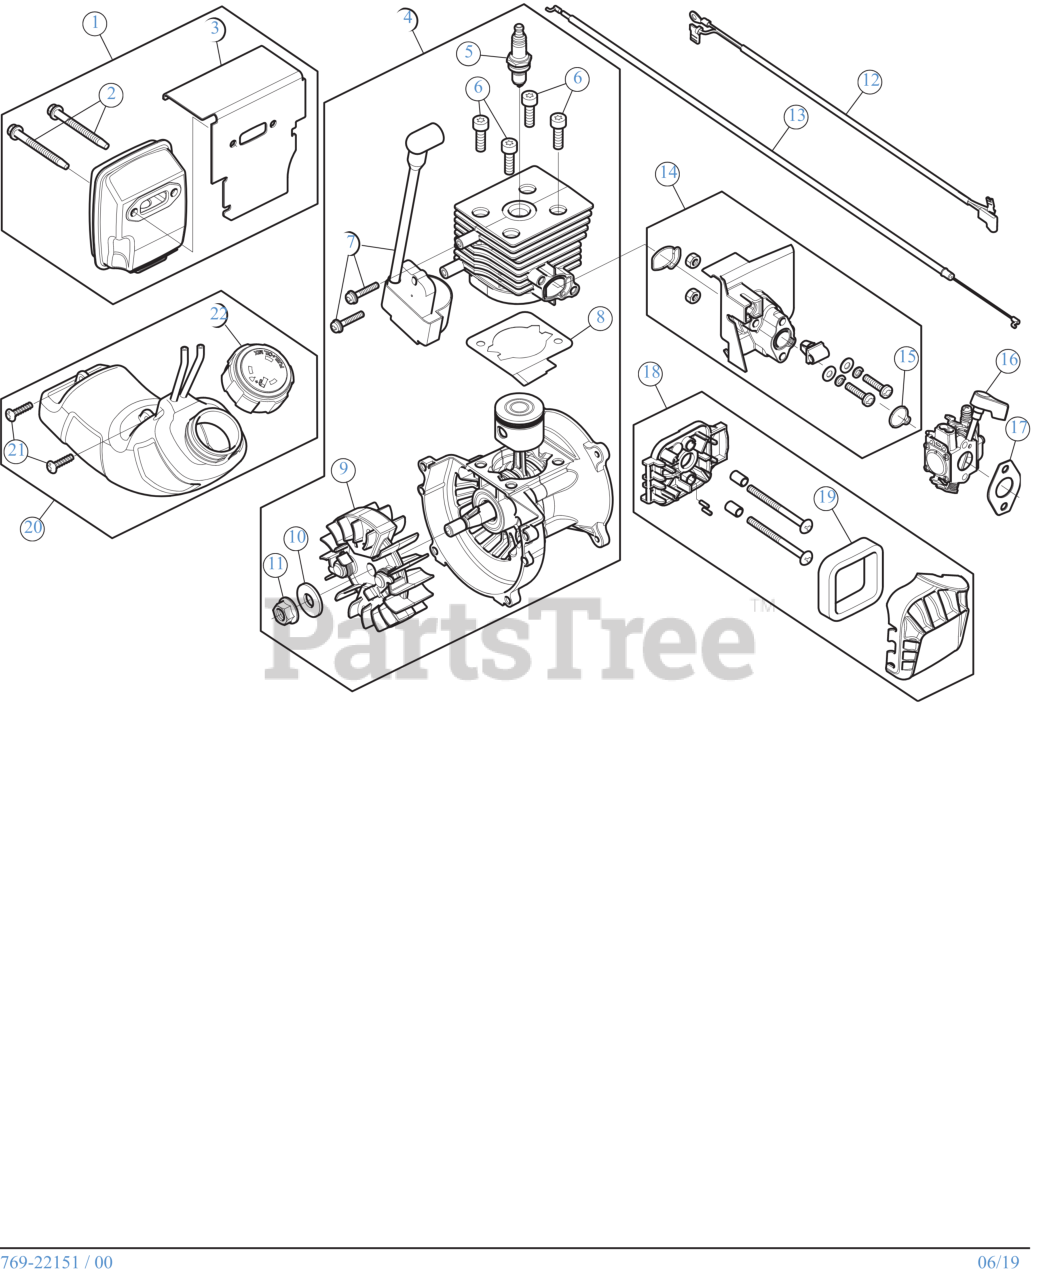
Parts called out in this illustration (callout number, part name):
1	MUFFLER ASSEMBLY 27CC
2	MUFFLER SCREW
3	MUFFLER GASKET
4	SHORT BLOCK
5	SPARK PLUG
6	SCREW 1/4 x 20 x .8125
7	MODULE ASSEMBLY
8	GASKET CYL
9	FLYWHEEL ASSEMBLY
10	WASHER .406X1.0X.095
11	NUT 3/8-24
13	THROTTLE CABLE
14	INTAKE ASSEMBLY
16	CARBURETOR ASSEMBLY
17	GASKET CARB
18	AIRCLEANER ASSEMBLY
20	FUEL TANK ASSEMBLY
21	SCREW 8-16 x 3/4
22	ASSEMBLY, FUEL CAP (RED TOP)
